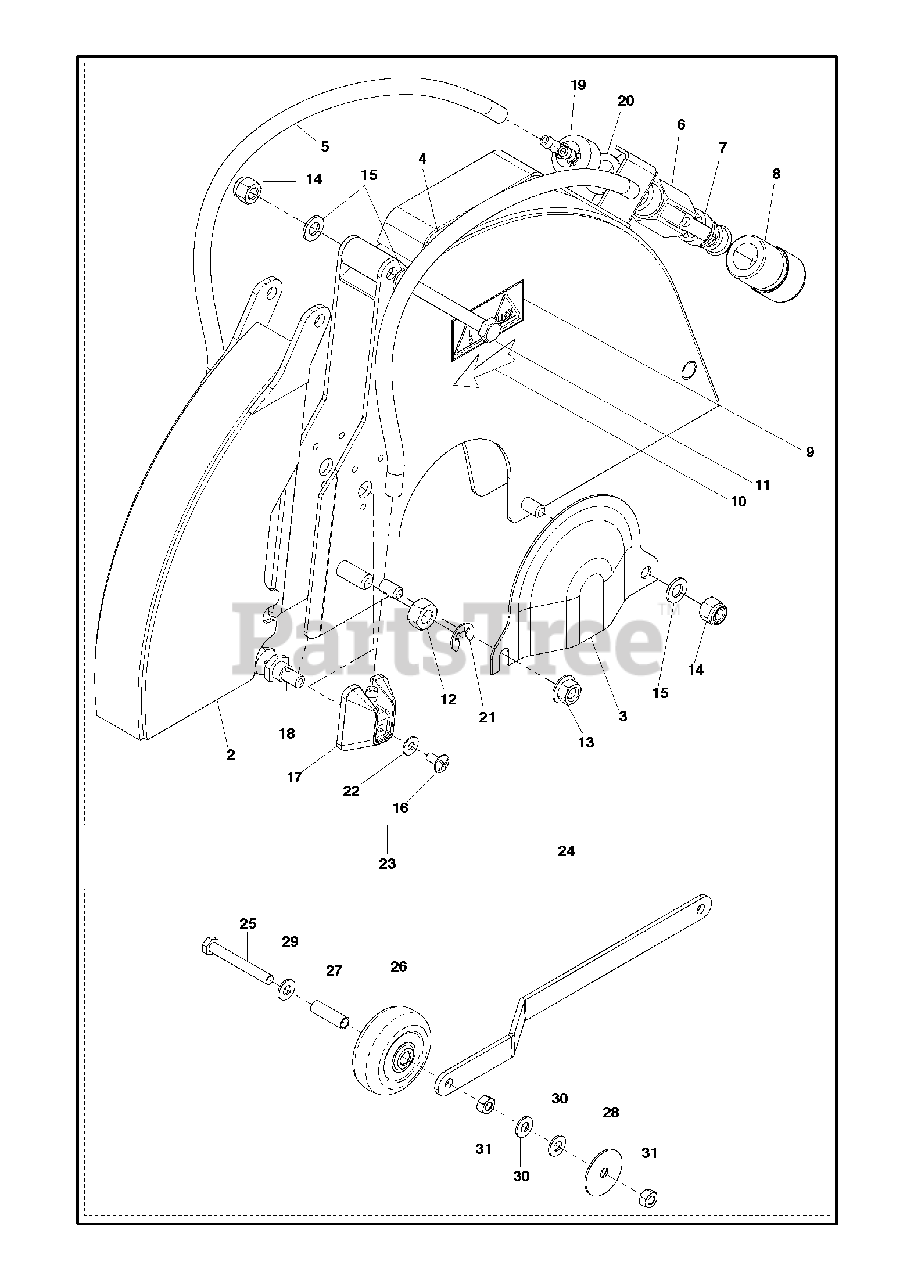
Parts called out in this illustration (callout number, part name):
13	HEXAGON NUT FLANGE
14	HEXAGON LOCKING NUT
15	WASHER
16	SCREW CRPANM
22	WASHER
29	WASHER
31	WASHER
